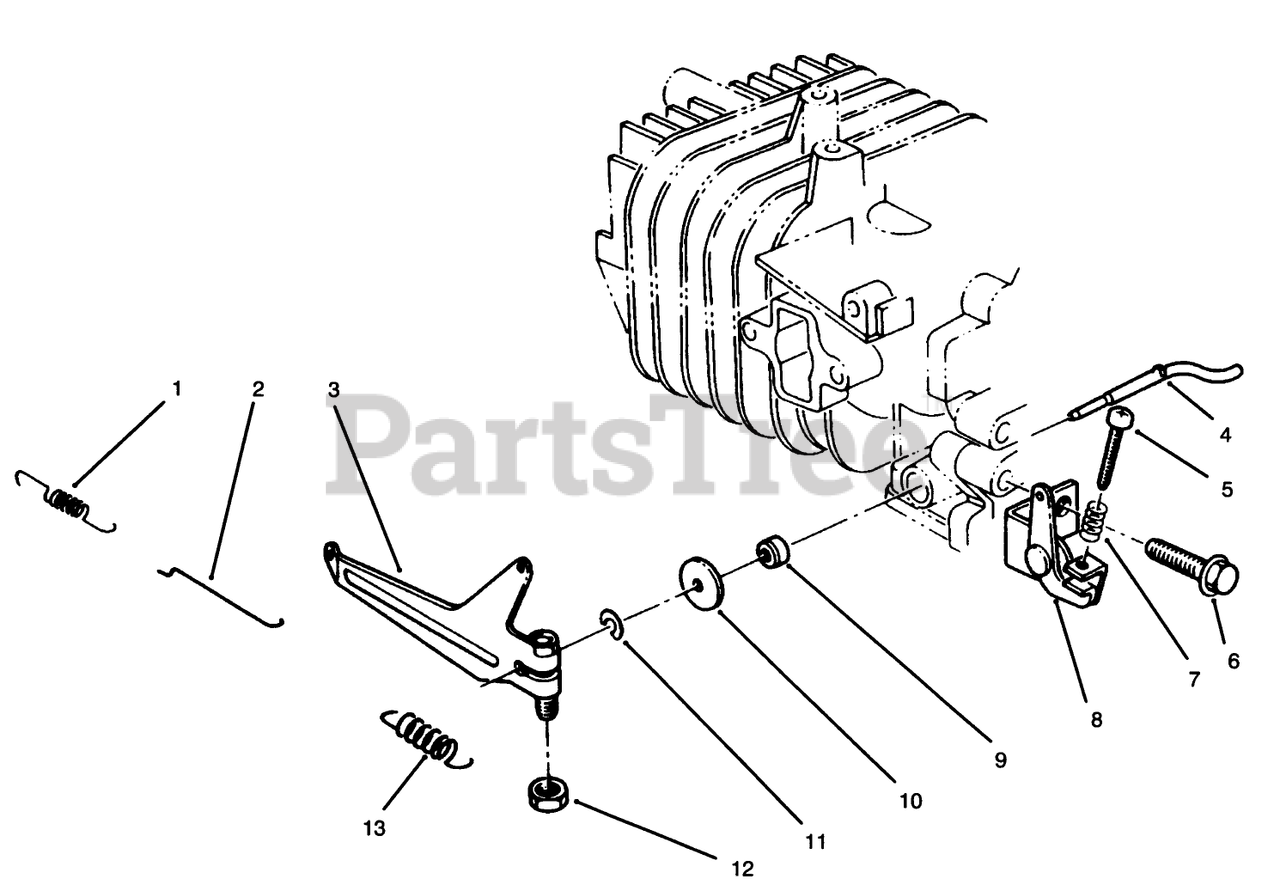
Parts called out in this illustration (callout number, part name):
2	CARB ROD
4	SHAFT
5	SCREW
7	SPRING
8	GOV SPR BRKT
9	SEAL-OIL
10	WASHER
13	GOV SPRING
